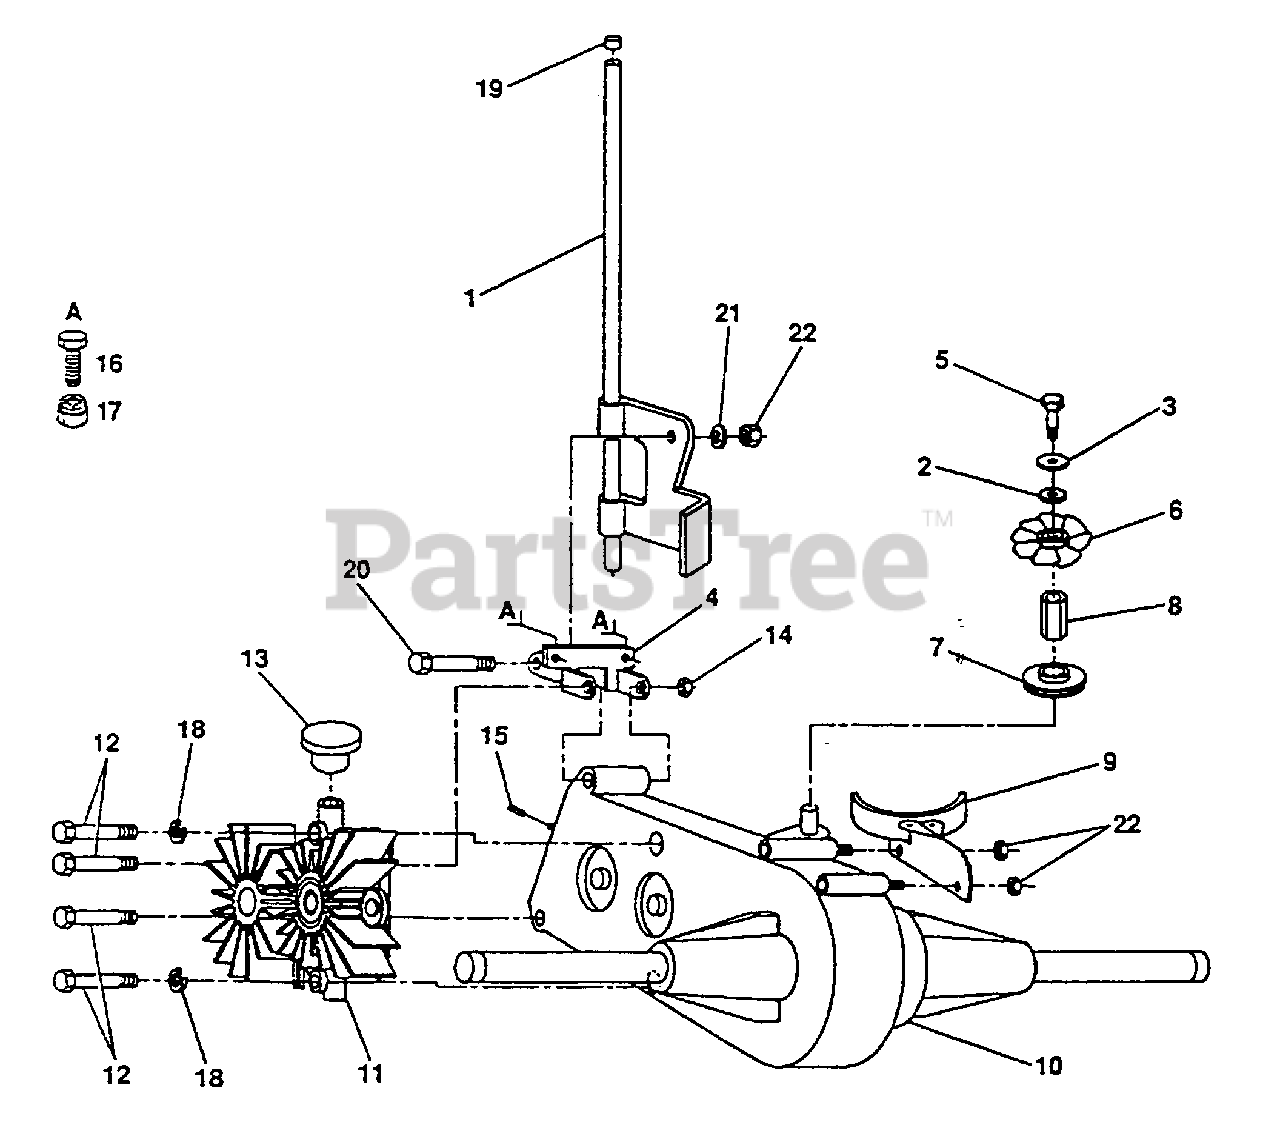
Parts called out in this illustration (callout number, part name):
1	Free Wheel Control Assembly (AYP part number)
2	Washer 9/32 x 1-1/4 x 16 Gauge (AYP part number)
3	Washer, Lock 1/4 (AYP part number)
4	Bracket, Pnt., Mounting, Differential (AYP part number)
5	Bolt, Hex 1/4-20 UNC x 3/4 (AYP part number)
6	Fan, Hydro, 8" (AYP part number)
7	Pulley, Transaxle (AYP part number)
8	Standoff, Fan, Hydro (AYP part number)
9	Guard Assembly, Belt (AYP part number)
10	Differential Assembly (AYP part number)
11	Pump Assembly (AYP part number)
12	Bolt, Hex, Fin 5/16-18 UNC x 4-1/2 (AYP part number)
13	Reservoir, Pump (AYP part number)
14	Nut, Crownlock 5/16-18
15	Spring, Compression (AYP part number)
16	Bolt 3/8-16 x 3/4 (AYP part number)
17	Nut 3/8-16 UNC
18	Washer, Lock (AYP part number)
19	Cap (AYP part number)
20	Bolt, Shoulder 1/4-20 UNC (AYP part number)
21	Washer, Nylon (AYP part number)
22	Nut, Crownlock 1/4-20 UNC (AYP part number)
